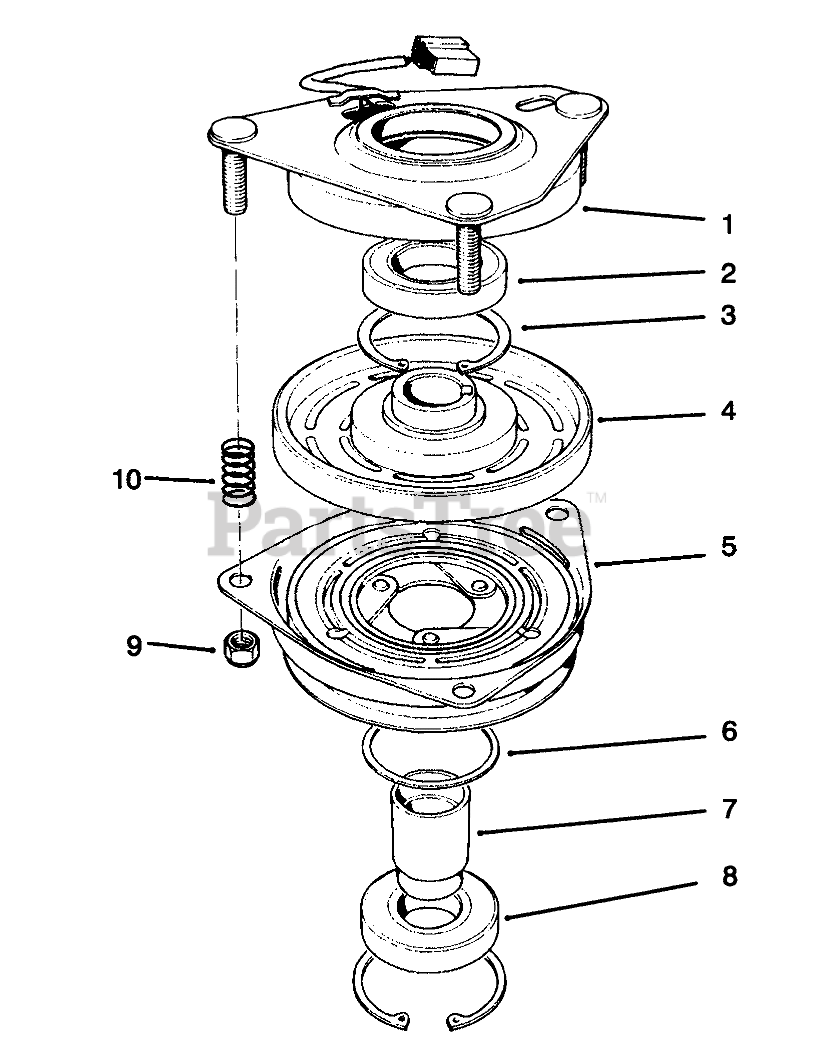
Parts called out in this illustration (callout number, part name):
1	Field Ass-y (Incl. Ref. #2 & 3)
2	BEARING-FIELD
3	RING-RETAINING
4	Field Coil, Rotor & Bearing Assembly (Incl. Ref. #1)
5	Armature & Pulley Assembly (Incl.Ref. #3, 6, 7, &8)
6	SPACER-BEARING, PULLEY
7	COLLAR-BEARING
8	BEARING-PULLEY
9	NUT-HEX
10	SPRING
